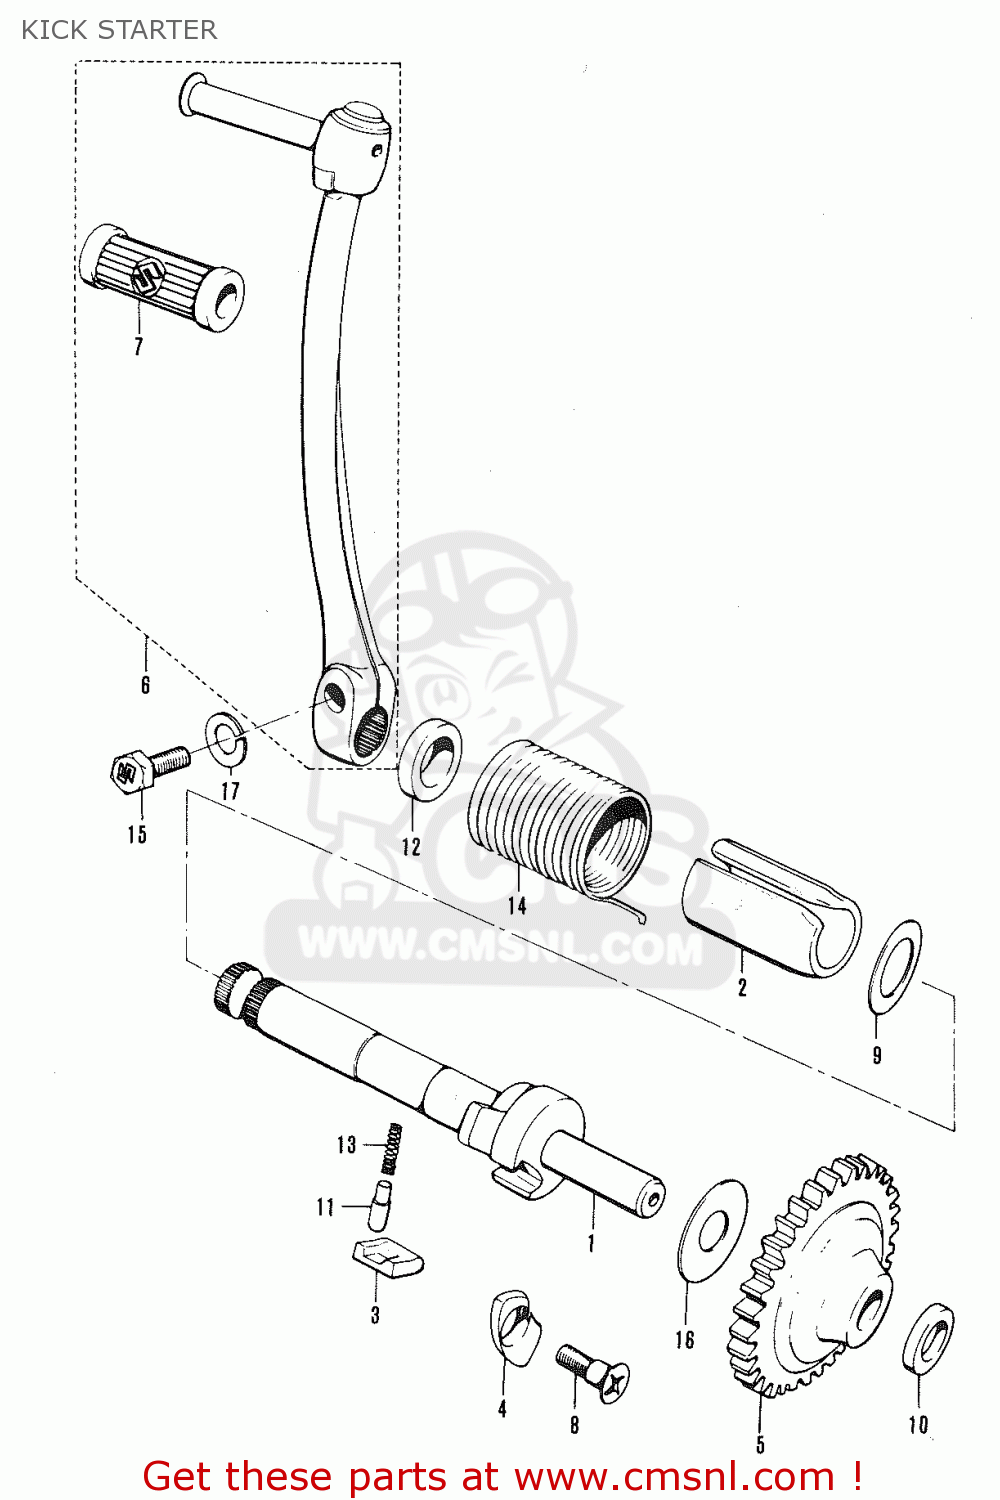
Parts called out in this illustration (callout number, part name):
1	SHAFT,KICK STARTER
2	GUIDE,KICK STARTER SFT SPRING
3	STARTER,KICK
4	LIFTER,KICK STARTER PAWL
5	GEAR,KICK STARTER DRIVE
6	LEVER ASSEMBLY,KICK STARTER
7	RUBBER,KICK STARTER PEDAL
8	SCREW(6X19)
9	WASHER(16X30X1)
10	SPACER
11	PIN(5X15.5)
12	SEAL,OIL(16X30X8)
13	SPRING
14	SPRING
15	BOLT
16	WASHER
17	LOCK WASHER
